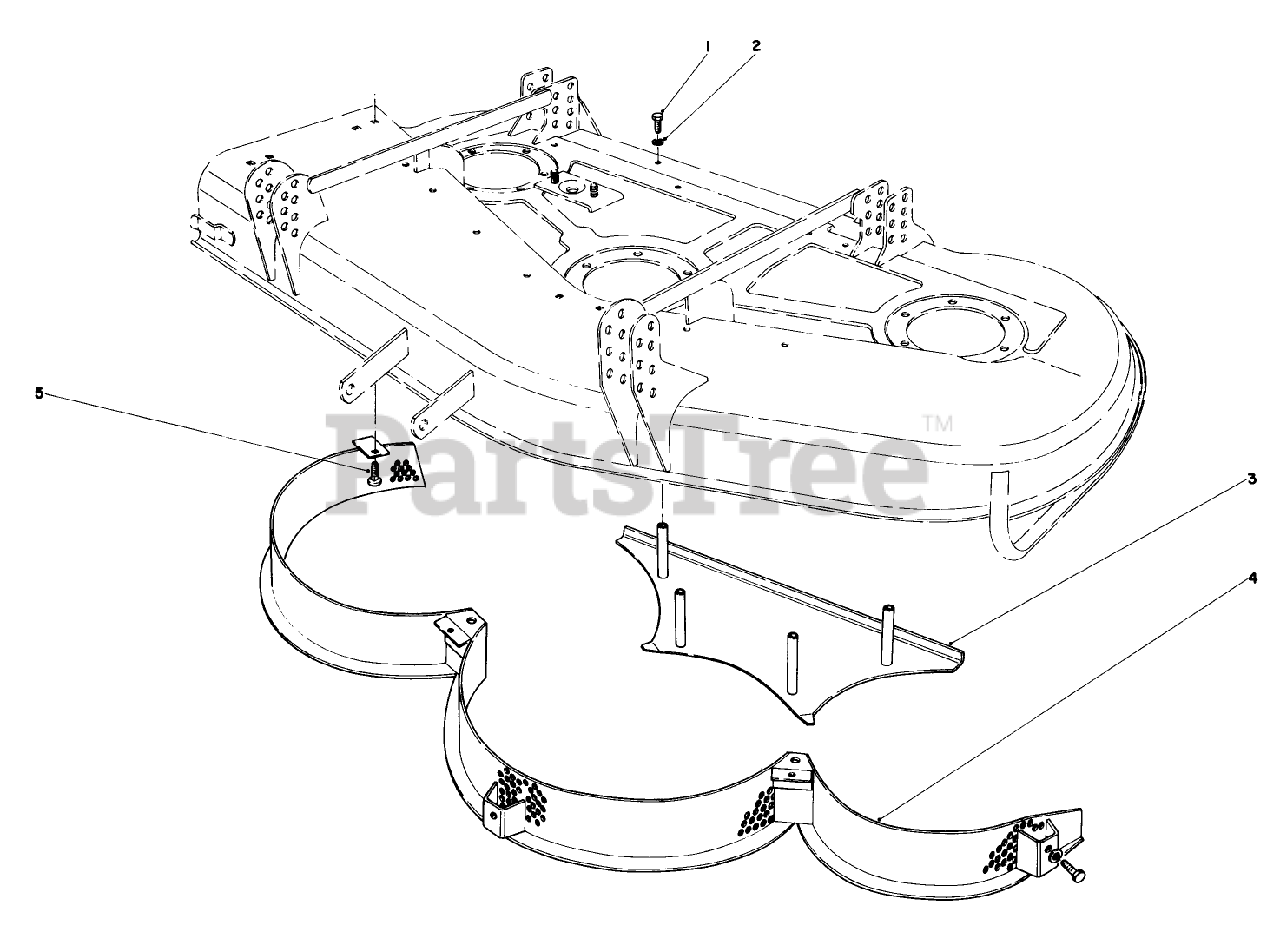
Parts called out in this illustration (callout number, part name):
1	SCREW-HH
2	WASHER-LOCK
3	Bottom Rear Shelf
4	Mulcher Screen
5	BOLT-CARR
